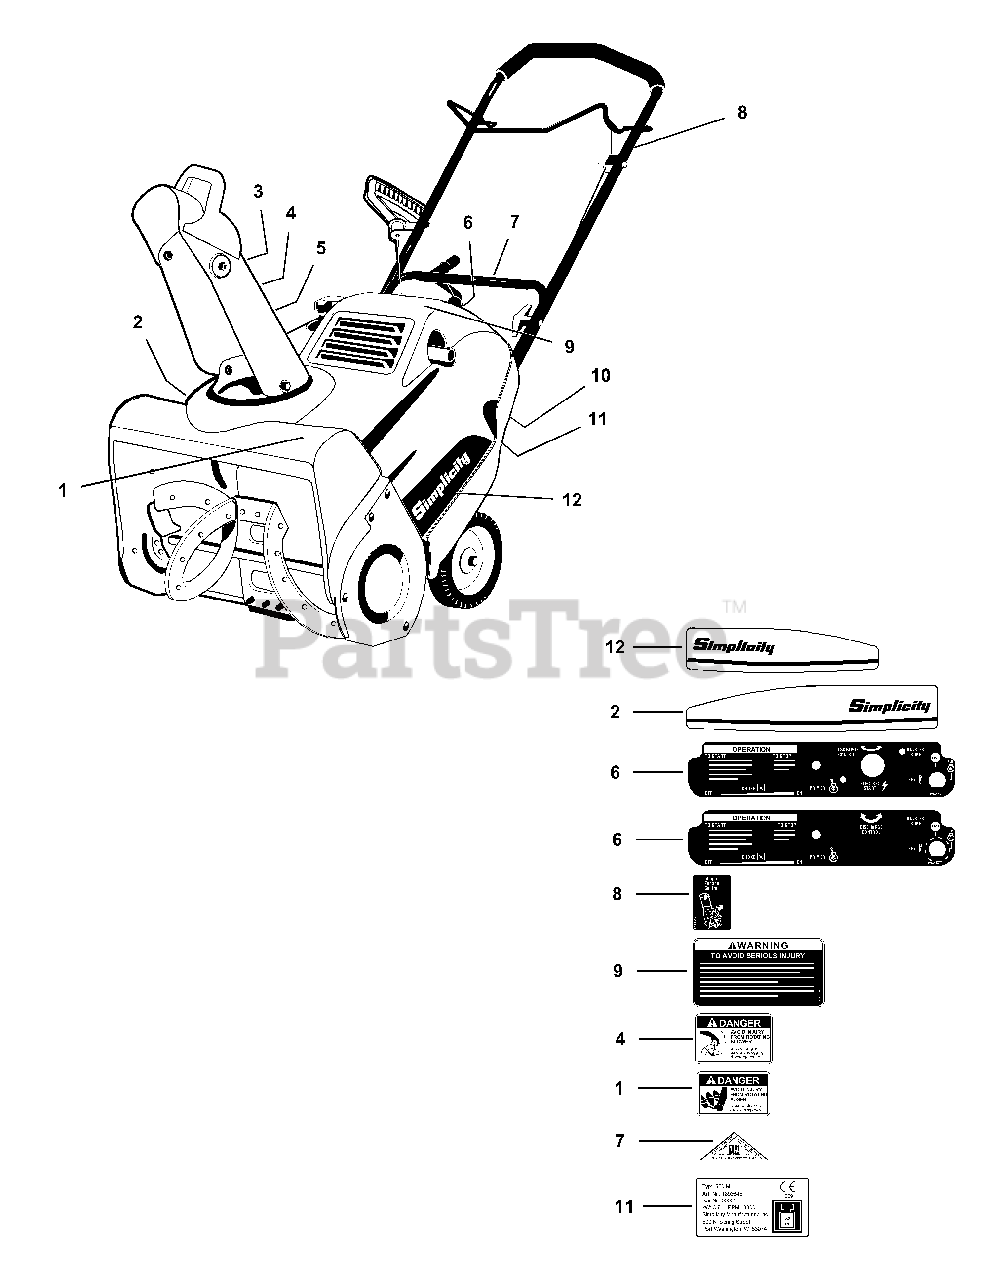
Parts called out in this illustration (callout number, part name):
1	DECAL, Danger, Auger
2	DECAL, Logo, R.H.
3	DECAL, Power-Mass (Export Models Only)
4	DECAL, Danger, Discharge Chute
5	DECAL, C.E. (Export Models Only)
6	DECAL, Console (Electric Start Models)
6	DECAL, Console (Manual Start Models)
7	DECAL, OPEI
8	DECAL, Auger Control
9	DECAL, Warning
10	DECAL, Compliance
11	SERIAL No.
12	DECAL, Logo, L.H.
